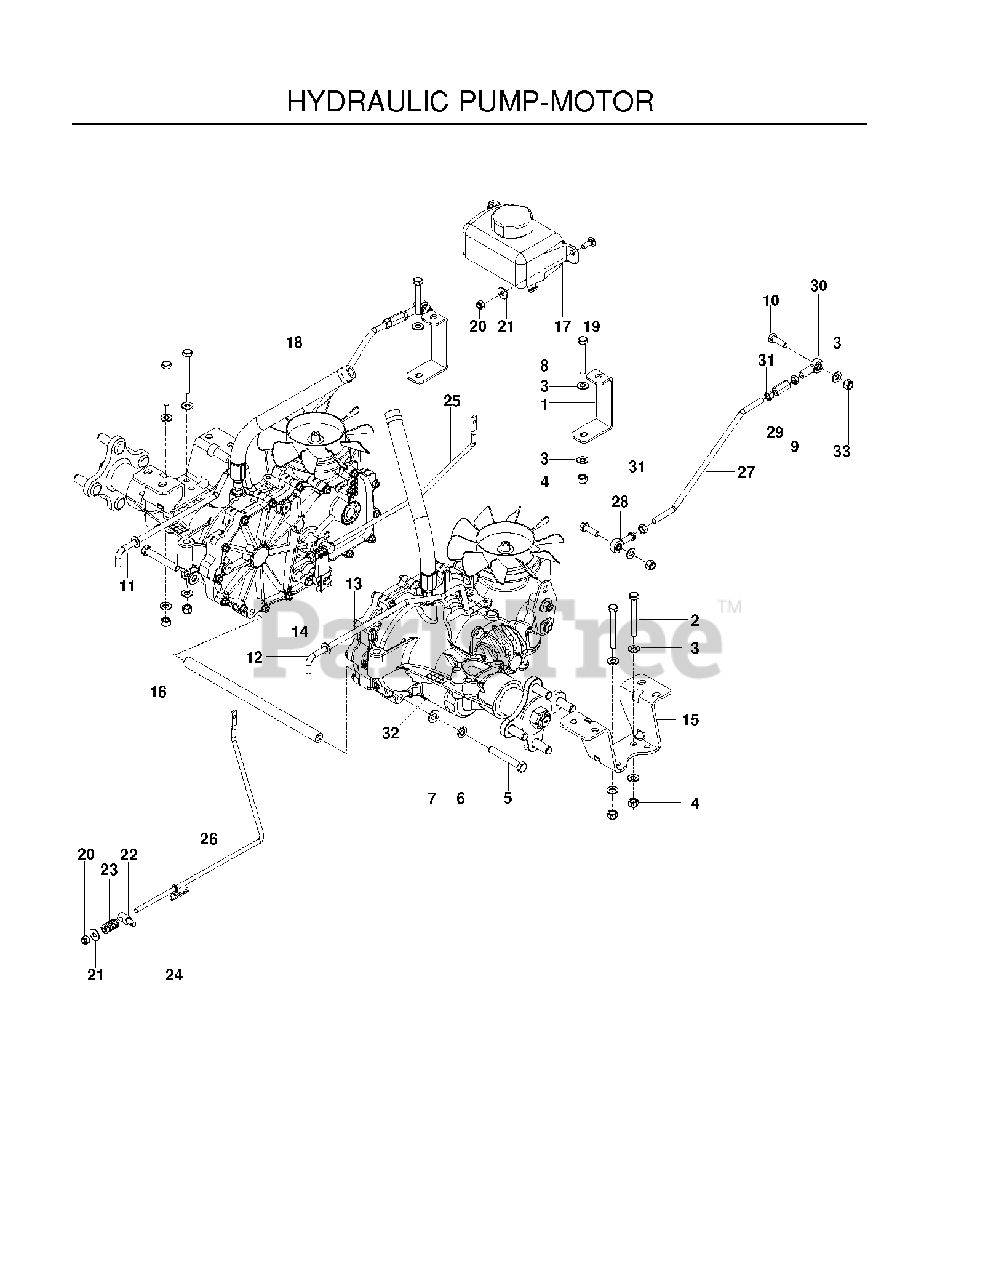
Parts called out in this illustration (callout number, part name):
1	SUPPORT.FRONT.TRANS.BLACK.
2	HCS 5/16C X 2-3/4
3	FLAT WASHER 5/16 SAE
4	NUT 5/16 NYLOC
5	HCS 3/8C X 2 1/2
6	SLW 3/8 STD
7	WASHER 3/8 SAE FLAT
8	CAPSCREW
9	NUT 5/16F LEFTHAND
10	HCS 5/16C X 1
11	ROD, BYPASS, RT
12	ROD, BYPASS, LT
13	HG_TRANS, ZT-2800 RT
14	HG_TRANS, ZT-2800 LEFT
15	EZT MOUNT, REAR, BLACK
16	SPACER TUBE, EZT, 11.08
17	HG_EXPANSION TANK W/CAP
18	HOSE ASSY
19	RHSNB 1/4C X 3/4
20	NUT 1/4-20 NYLOC
21	WASHER 1/4 FLAT
22	BRAKE SWIVEL
24	HAIRPIN #2
25	LINKAGE.BRAKE.LT
26	LINKAGE, BRAKE RT
27	Motion Control Rod
28	RH ROD END
29	ROD END COUPLER
30	ROD.END.LH
31	NUT 5/16F
32	HG_FILTER, ZT4800
33	5/16-18 THIN PROF NY
